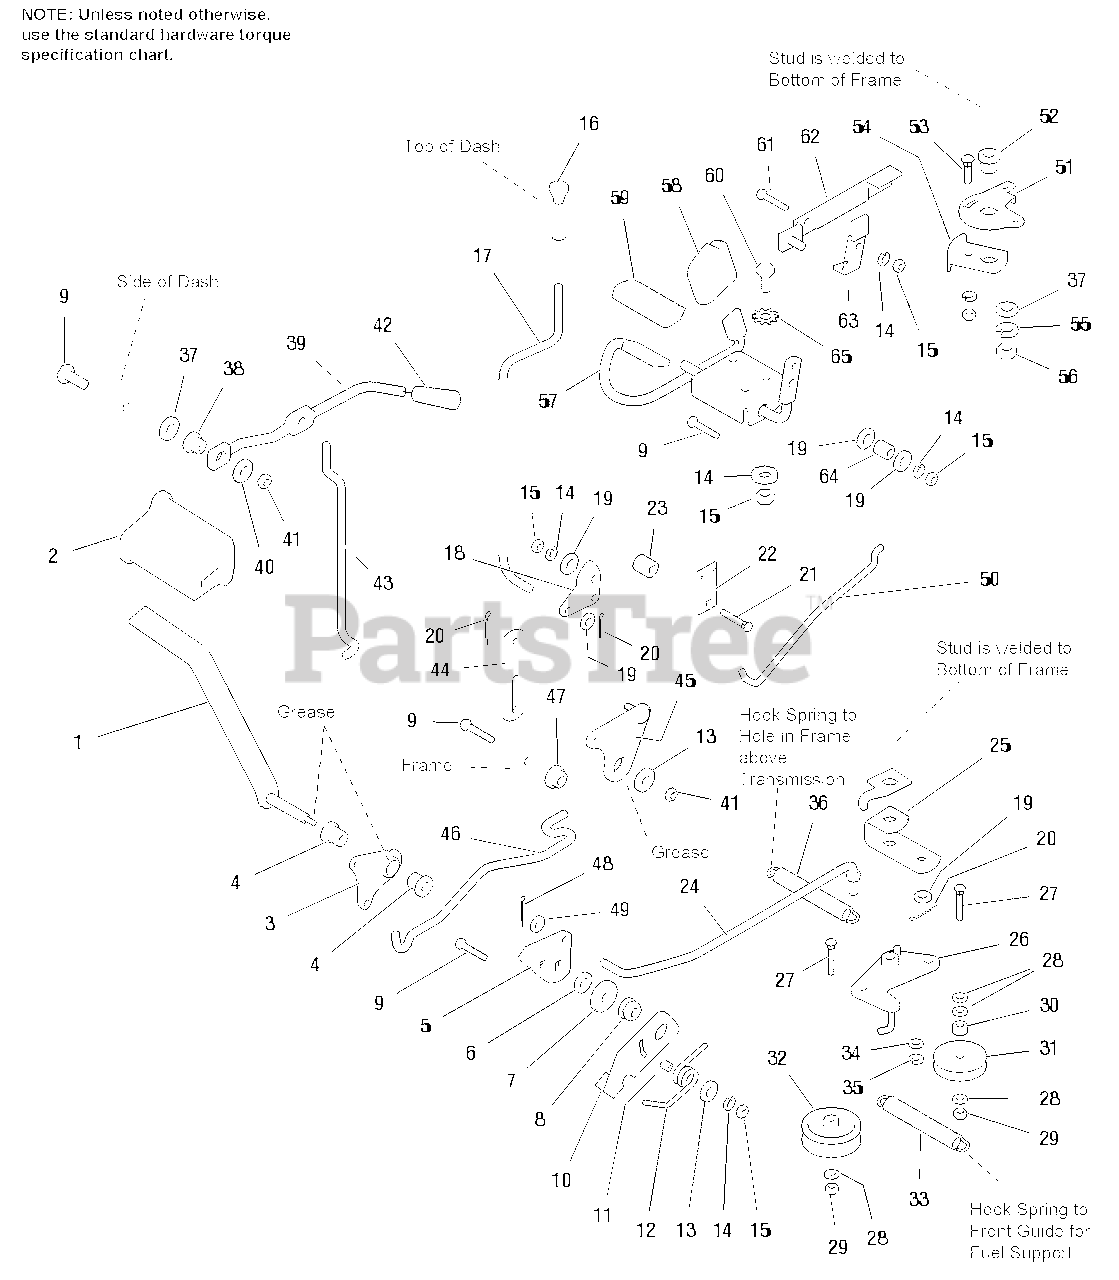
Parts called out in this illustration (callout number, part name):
1	FOOT PEDAL & SHAFT ASSY.
2	FOOT PEDAL PAD
5	ARM, Foot Pedal
6	WASHER, Plain, 3/8
7	WASHER, 3/8
8	NUT, Hex Nylon Lock, 3/8-16
9	CARRIAGE BOLT, 5/16-18 x 1-1/4
10	SWITCH, Actuator
11	SPACER, 21/64 x 1/2 x 7/16
12	SPRING, Torsion
13	WASHER, 5/16
14	LOCKWASHER, 5/16
15	NUT, Hex, 5/16-18
18	BELLCRANK, Cruise
19	WASHER, 5/16
20	COTTER PIN, 3/32 x 3/4
21	CARRIAGE BOLT, 5/16-18 x 1
22	PLATE, Cruise Lock Light Switch
23	SPACER, 21/64 x 1/2 x 7/32
24	ROD, Clutch
25	PIVOT ASSY, Clutch / Brake
26	PIVOT ASSY, Idler
27	CARRIAGE BOLT, 3/8-16 x 1-3/4
28	WASHER, Plain, 13/32
29	NUT, Hex Flange, 3/8-16
30	SPACER, 25/64 x 29/32 x 11/32
32	PULLEY, Idler
33	SPRING, Extension
34	WASHER, 5/8
35	KLIPRING, Extension
36	SPRING, Extension
37	WASHER, 3/8
38	SPACER, 11/32 x 3/4 x 1/2
39	ROD, Lift Handle
40	WASHER, Flat, 5/16
41	NUT, Hex Nylon Lock, 5/16-18
42	KNOB, Rod Lift
43	ROD, Link Lift
44	LINK, Lift, Upper
45	CAM & WELD-PIN ASSY
46	LINK, Lift Rod
47	SPACER, 11/32 x 1-1/4 x 21/32
48	COTTER PIN
49	WASHER, Plain, 1/4
50	ROD, Cruise
51	BRACKET, Adjustment, Lock Plate
52	SPACER, 25/64 x 15/16 x 21/32
53	CARRIAGE BOLT, 5/16-18 x 7/8
54	LOCK PAD ASSY
55	LOCKWASHER, 3/8
56	NUT, Hex, 3/8-16
57	PEDAL ASSY, Foot
58	PAD, Foot Pedal, Reverse
59	PAD, Foot Pedal, Forward
60	CAPSCREW, Hex Hd, 5/6-18 x 3/4
61	CARRIAGE BOLT, 5/16-18 x 3/4
62	LOCK PLATE ASSY
63	BRACKET, Lock Plate Assy
64	SPACER, 21/64 x 9/16 x 5/16
65	LOCKWASHER, External Tooth, 5/16
